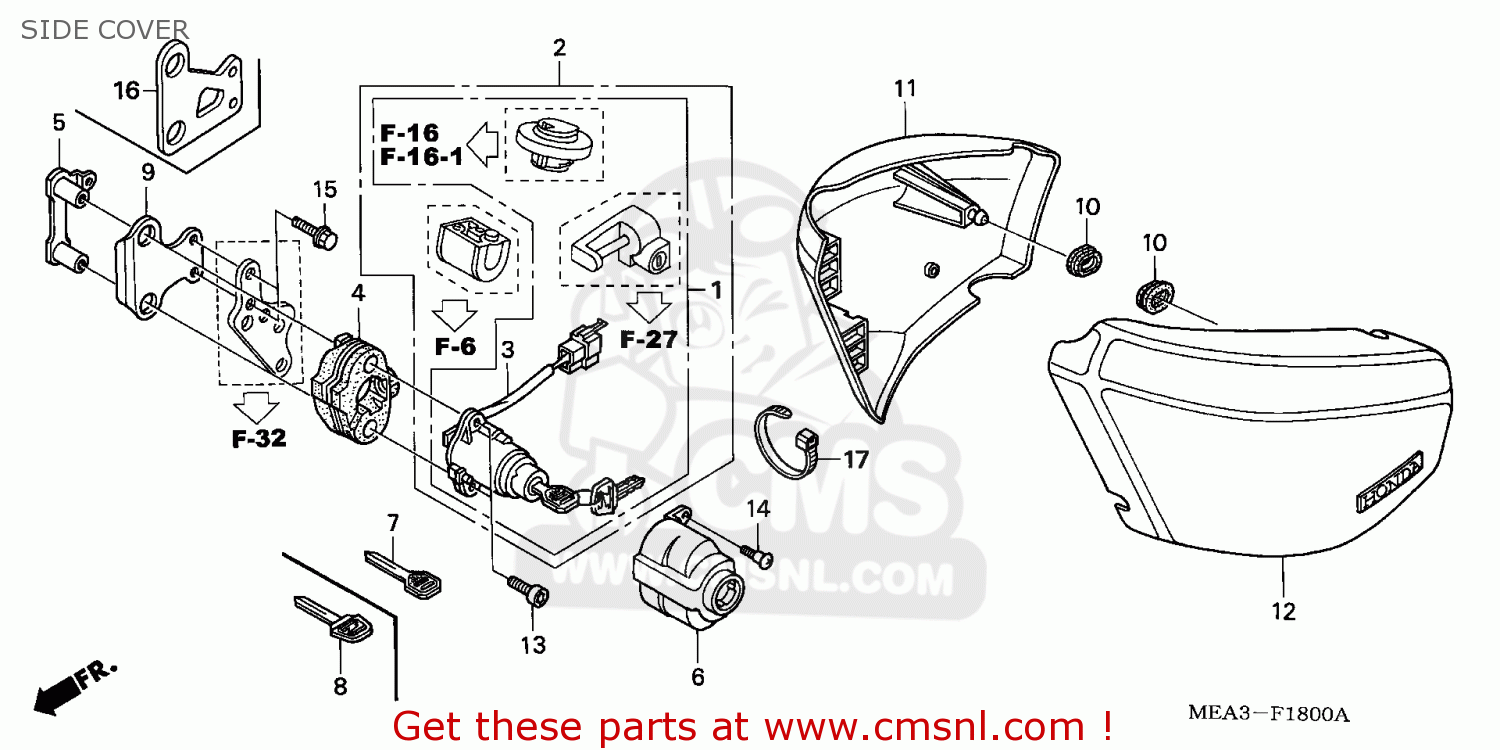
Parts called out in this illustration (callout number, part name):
1	KEY SET
3	SWITCH ASSY,COMB
4	BASE,COMBI SW
5	COLLAR,COMBI SW
6	COVER,COMBINATION
7	KEY,BLANK NO.1
8	KEY,BLANK (NO.1)
9	STAY,IGN.SW.
10	GROMMET,RR.COVER
11	COVER SET, R. SIDE (
12	COVER SET, L. SIDE (
13	BOLT,TORX,6X14
14	SCREW,RR,COVER
15	BOLT,FLANG,6X16
